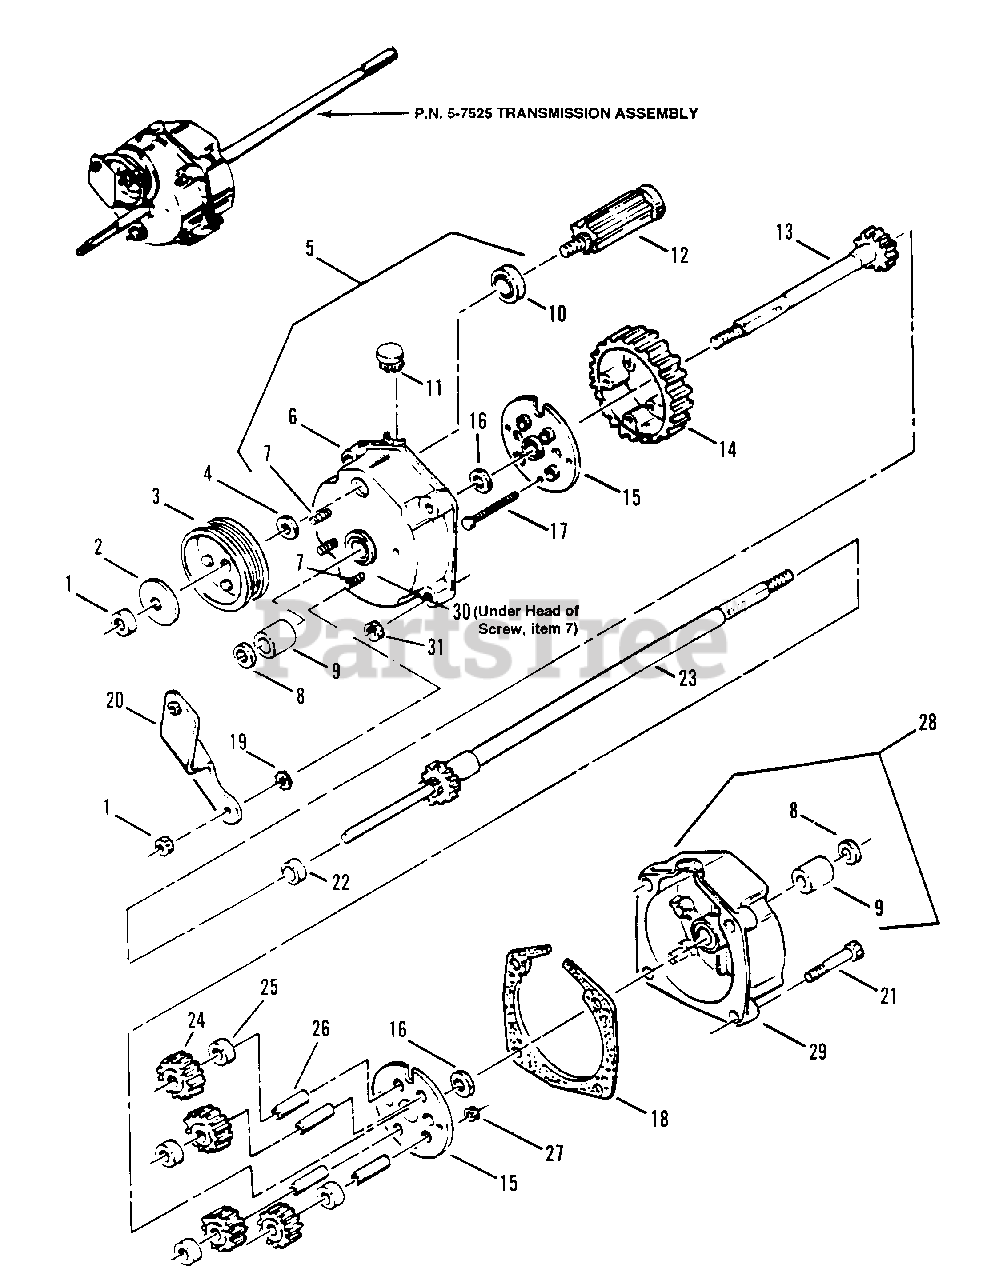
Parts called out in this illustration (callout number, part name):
1	NUT, 5/16-24 Hex Lock
2	WASHER, Spring
3	PULLEY, Poly-Vee Belt
4	WASHER, Spring
5	ASSEMBLY, Housing Right
6	HOUSING, Right Side
7	SCREW, 5/16-24 x 1-1/8" Rib Neck
8	SEAL, 5/8 I.D.
9	BEARING, Differential
10	BEARING, Ball
11	PLUG, Housing
12	GEAR, Input
13	AXLE, Short
14	GEAR, Differential (46 Tooth)
15	PLATE
16	WASHER, Thrust
17	SCREW, #10-32 x 1-1/2" Hex Head Cap
18	GASKET, Housing
19	WASHER, 5/16 Internal/External Tooth Lock
20	BRACKET, Differential
21	SCREW, 1/4-20 x 1-1/4" Self-Tapping
22	SPACER, Axle Gear
23	AXLE, Long
24	GEAR, Pinion (12 Tooth)
25	SPACER, Pinion Gear
26	SHAFT, Pinion
27	NUT, #10-32 Hex Lock
28	ASSEMBLY, Housing Left
29	HOUSING, Left Side
30	GASKET, 5/8 O.D.
31	NUT, 1/4-28 Hex Lock
57525	ASSEMBLY, Transmission
